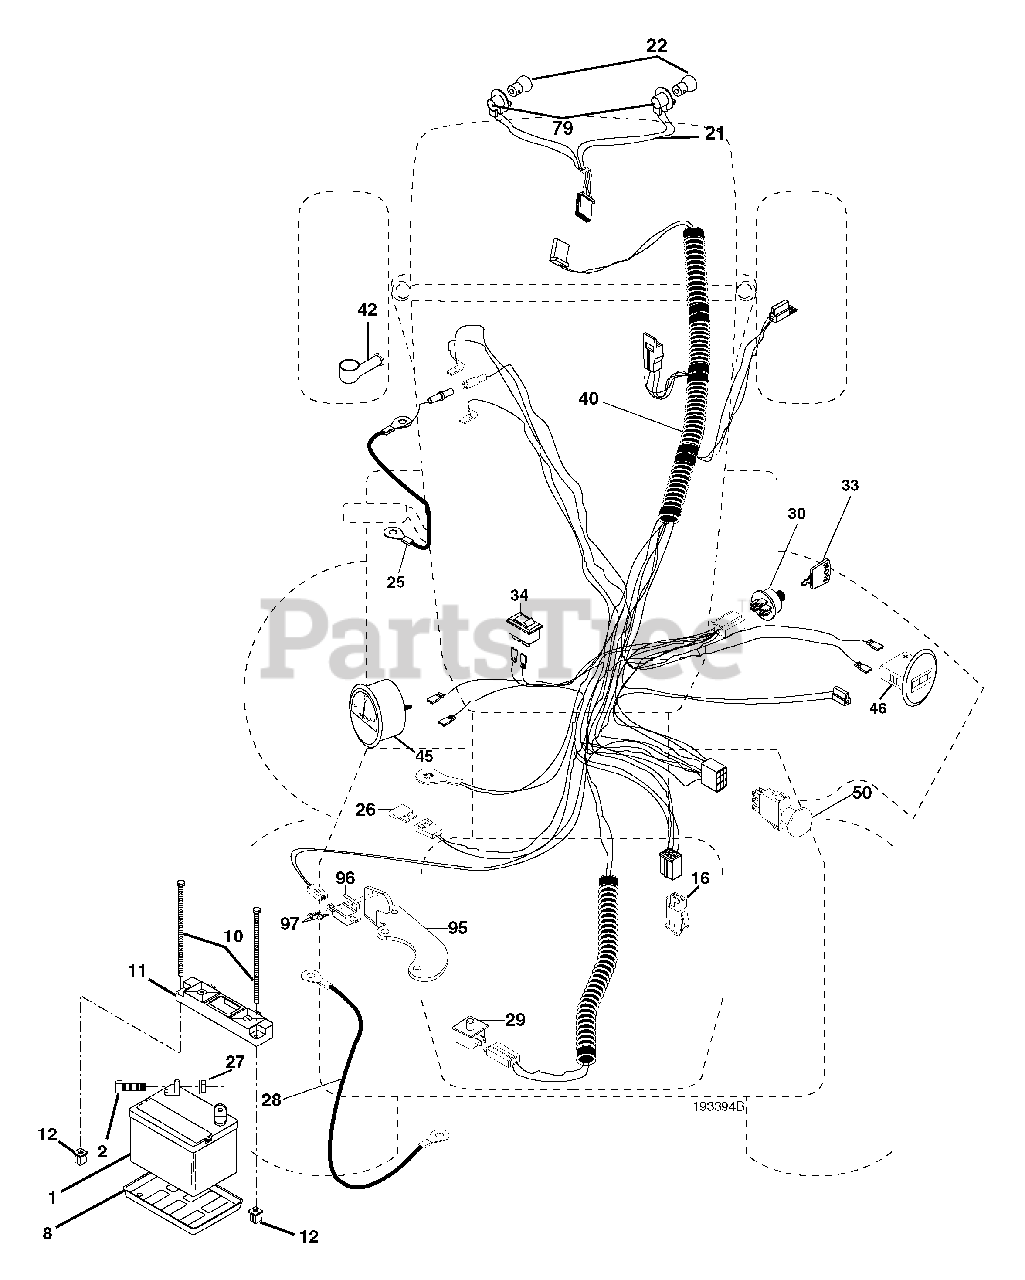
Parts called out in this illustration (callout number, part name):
1	Battery
2	Bolt Hex Head 1/4-20 x 3/4
8	Tray, Battery
10	Bolt, Battery Front 1/4-20 x 7.5 Zinc
11	Holddown Battery Front Mount
12	Nut, Push Nylon 1.4" Battery Front
16	Switch Interlock Push-In
21	Harness Socket Light w/4152J
22	Bulb Light
27	Nut Keps Hex 1/4-20
28	Cable Bolt Ground
29	Switch, Seat
30	Switch, Ign
34	Switch Light/Reset B/B/Red
40	Harness Ign.
42	Cover, Terminal Red
50	Switch, PTO
79	Bulbholder Asm
92	Harness Pigtail Reverse Switch
93	Screw 10-14 x 2.0
94	Modual Reverse ROS
